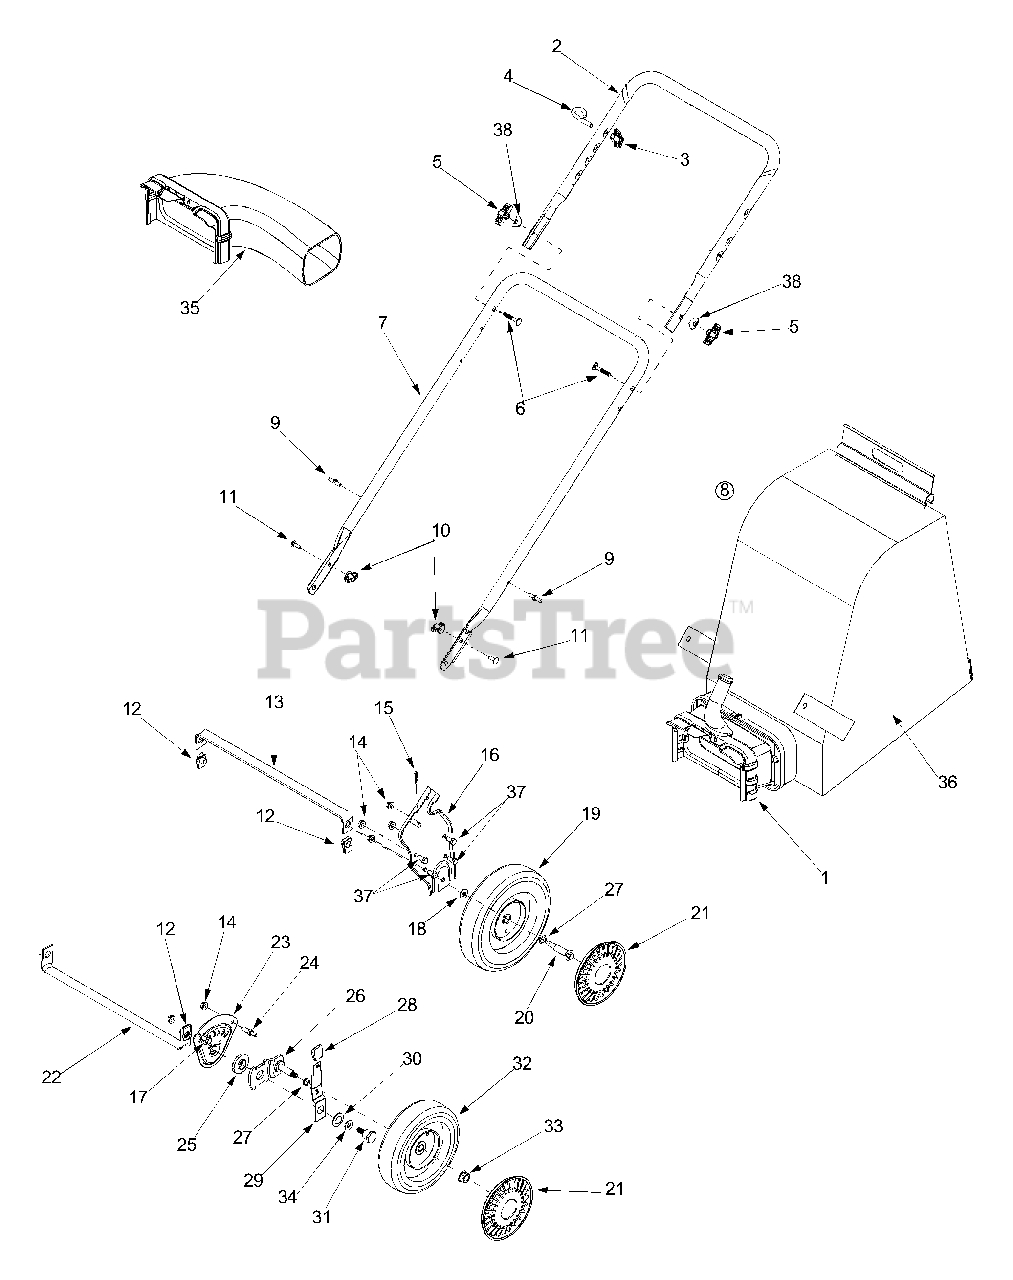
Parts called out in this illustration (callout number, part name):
1	Chute Assembly
4	Eye Bolt
5	Handle Knob 5/16-18
6	Carriage Bolt
8	Bag Assembly
9	Studs
10	Wing Nut 1/4-20
11	Carriage Screw 1/4-20 x.75
12	Lock U-Clip Nut 3/8-16
15	Cotter Pin
17	Hex Cap Screw 5/16-18 x.625
18	Bell Washer.401 ID x.870 OD
19	Wheel 9 x 2
20	Shoulder Screw 3/8-16
21	Hubcap
25	Height Adjustment Bearing
26	Pivot Arm Assembly
27	Wave Washer.531 ID x.781 OD
28	Height Adjustment Knob
29	Spring Lever
30	Bell Washer.760 ID x.25OD
31	Shoulder Screw.750 ID x.625 OD
32	Wheel 8 x 2
33	Flange Lock Nut 3/8-16
34	Thrust Washer.375 ID x.70 OD
35	Blower Chute Assembly
36	Bag
37	Screw 5/16-18 x.750
38	Saddle Washer
